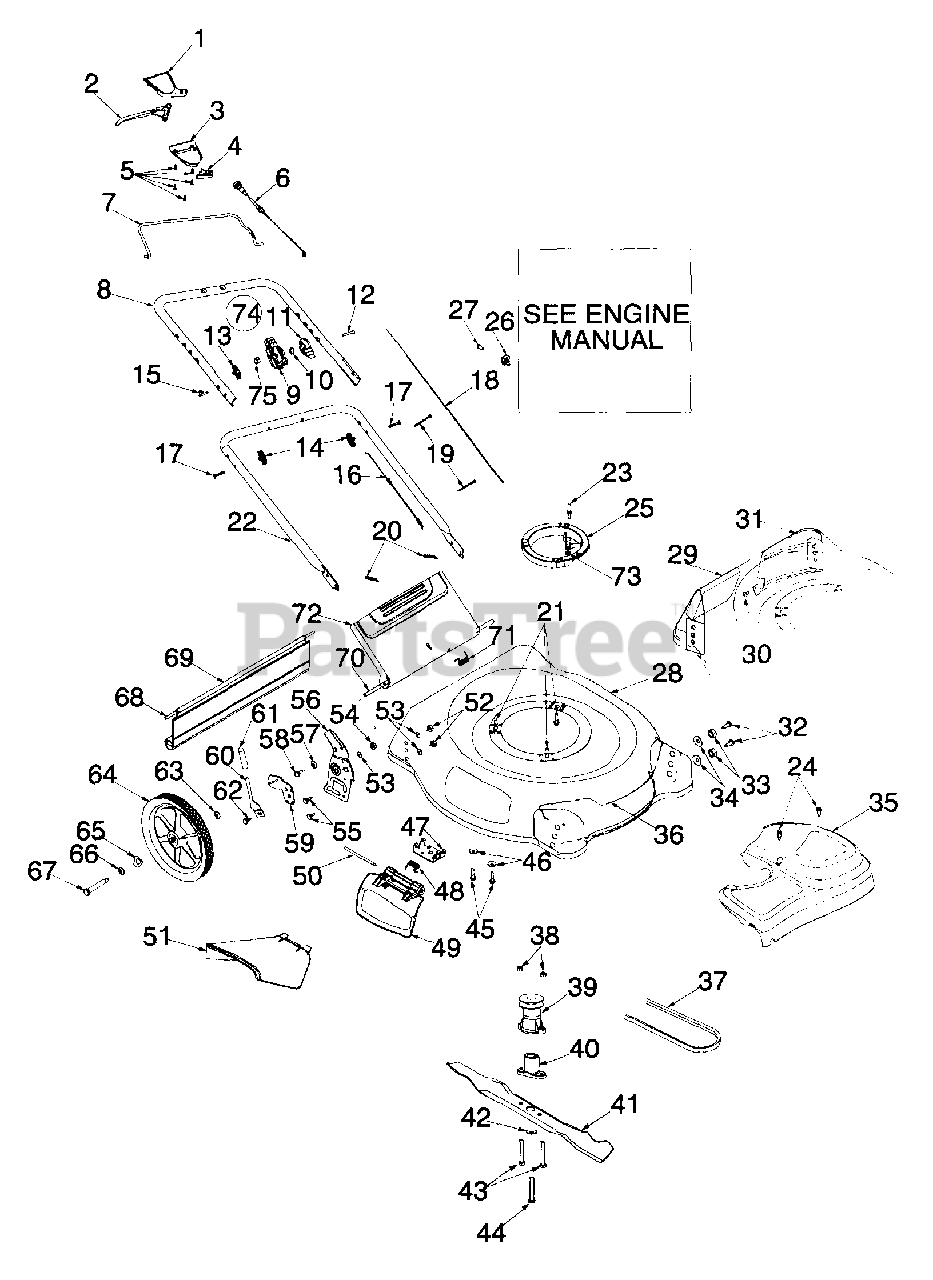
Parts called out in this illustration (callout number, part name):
1	Upper Drive Cover
2	Drive Lever
3	Lower Drive Cover
4	Mounting Cap
5	Screw #10-12: .75
6	Drive Cable
9	Throttle Hsg.
10	Curved Washer .663 x .980 x .014
11	Throttle Lever
12	Screw Oval C-Sunk 1/4-20 x 1.61
14	Knob
15	Eye Bolt 1/4-20
16	Throttle Cable: 55" (B&S)
17	Carriage Bolt 5/16-18 x 2.0
18	Control Cable: 39" (B&S)
19	Tie Cable
20	Cotter Pin
21	Tapp Screw w/Hex Lock Wash
23	Pin-Belt Keeper
24	Screw #12 x .457
25	Engine Spacer
26	Cable Clamp (B&S)
27	Hex Screw: T: #10-32 x .625 Lg. (B&S)
30	Scr: AB: 1/4-14: .625: Trustrx
32	Hex Screw 3/8-16 x .75
33	Bell Wash .39 x 1.13 x .062
34	Hex Nut 3/8-16
35	Trans Cover - Black
38	Hex Lock Nut 1/4-20
39	Drive Pulley
40	Blade Adapter Kit
41	21" Mulching Blade
42	Bell Washer .396 I.D. x 1.140 O.D. x .095
43	Hex Screw 1/4-20 x 1.50
44	Hex Screw 3/8-24 x 2.50
45	Tapp Screw 1/4-20 x .500
46	Bell Wash .265 x .75 x .062
48	Torsion Spring .290 ID x 1.95
49	Mulch Plug Ass'y.
50	Hinge Pin
51	Chute Deflector
52	Hex Nut 3/8-16
53	Bell Wash .39 ID x 1.38 OD
54	Hex Flange Lock Nut 3/8-16
55	Hex Screw w/wash 1/4-14 x .625
57	Bell Wash .265 x .75 x .062
58	Hex Screw TT 1/4-20 x .500
59	Pivot Bar RH
60	Height Adj Lever
61	Foam Grip
62	Shldr Screw .500 Dia x .434
63	Wash. .401 x .870 x .063
64	Wheel Comp. 14 x 2 Yellow Link Tread
65	Spring Washer .50 ID x 1.0 OD
66	Flat Washer .510 x 1.373 x .04
67	Shldr Screw .500 x 2.62 3/8-16
68	Wire
69	Rear Flap
70	Pivot Rod
71	Torsion Spring
74	Throttle Body Comp.
75	Hex Lock Nut, 1/4-20 Thd.
